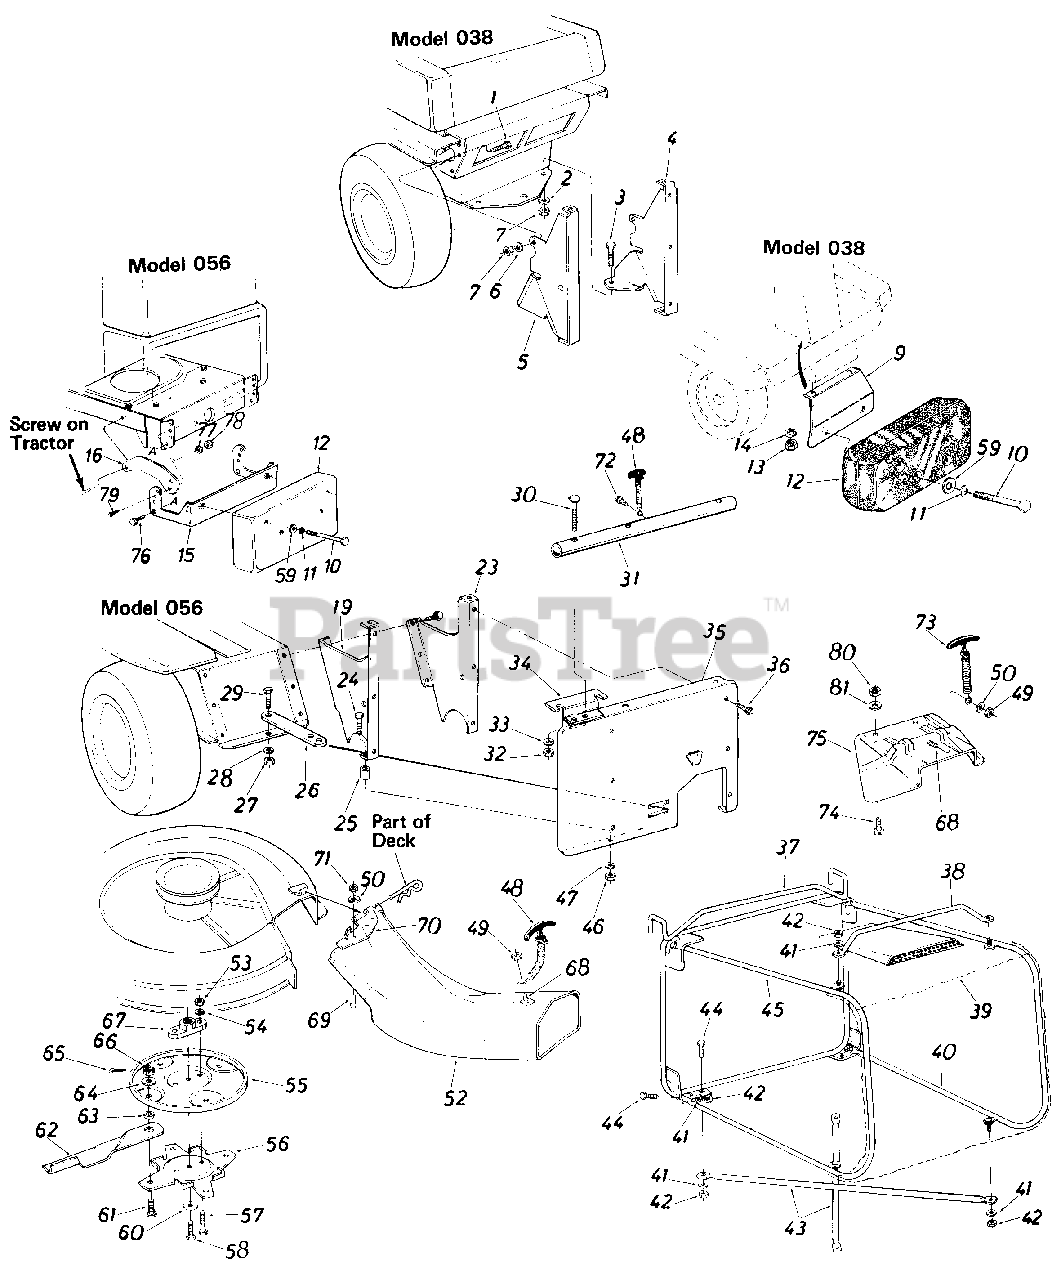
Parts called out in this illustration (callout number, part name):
1	Hex Bolt 5/16-18 x 1.0" Lg.*
2	L.-Wash. 5/16" I.D.*
3	Hex Bolt 5/16-18 x 1.0" Lg.*
4	Catcher Support Brkt - R.H.
5	Catcher Support Brkt - L.H.
6	L.-Wash. 5/16" I.D.*
7	Hex Nut 5/16-18 Thd.*
9	Counterweight Support Brkt. Ass'y
10	Hex Bolt 3/8-16 x 4.5" Lg.*
11	Belleville Wash. .40" I.D. x .88"O.D.
12	Counterweight 38 Ibs.
13	Hex Nut 5/16-18 Thd.*
14	L.-Wash. 5/16" I.D.*
15	Counterweight Support Brkt. Ass'y.
16	Tie Strap
19	Catcher Support Brkt. - L.H.
23	Catcher Support Brkt. - R.H.
24	Hex Bolt 5/16-18 x 1.50" Lg.*
25	Spacer .380" I.D. x .47" O.D. x 1.0" Lg.
28	L.-Wash. 1/2" I.D.*
29	Hex Bolt 1/2-20 x 1.0" Lg.*
30	Curved Carriag i301t ll6-l8 x 1.75" Lg.
33	L.-Wash. 5/16" I.D.*
34	Grass Catcher Support Plate
35	Rear Discharge Panel
36	Hex Wash. Hd. Self Tap. Scr. 1/4- 20 x .50" Lg.
37	Grass Catcher Frame Ass'y.
42	Hex L.-Nut 1/2-20 Thd
43	Bottom Cross Brace
44	Hex Bolt 1/4-20 x .62" Lg.*
47	L-Wash. 5/16" I.D.
48	Hook Latch Ass'y.
49	Hex L.-Nut 1/4-20 Thd.
50	Fl.-Wash. 1/4" I.D.*
52	R.D. Banana Chute Ass'y.
53	Hex Nut 5/16-24 Thd.*
54	L.-Wash. 5/16" I.D.*
55	Upper Blade Disc
58	Hex Bolt 3/8-24 x 1.0" Lg.
59	Fl.-Wash. .39" I.D. x 1.12" O.D .
60	Bell.-Wash. 39" I.D. x 1.38"
61	Shld. Bolt. .50" Dia. x .360 Spec.
62	30" Blade Tip
63	Spacer .505" I.D. x .75" O.D. x 1.25" Lg.
64	Fl.-Wash. .50" I.D. x 1.25" O.D.
65	Cotter Pin 3/32" Dia. x 1.0" Lg.*
66	Hex Slotted Nut 1/2-20 Thd.
67	Blade Adapter
68	Hex Bolt 1/4-20 x .50" Lg.*
69	Truss Mach. Scr. 1/4-20 x .50" Lg.*
72	Hex AB Tap Scr. 1/4 x .62" Lg.
73	Hook Latch Ass'y. 7" Lg.
74	Truss Mach. Scr. 1/4-20 x 50" Lg.*
75	R D Chute Extension
76	Hex Bolt 7/16-20 x 1.0" Lg.*
77	L.-Wash. 7/16" I.D.*
78	Hex Nut 7/16-20 Thd.*
79	Self-Tap. Scr. 5/16-18 x 1.0" Lg.
80	Hex L.-Nut 1/4-20 Thd.
81	Fl.-Wash. .281" I.D. x .50" O.D. x .063
